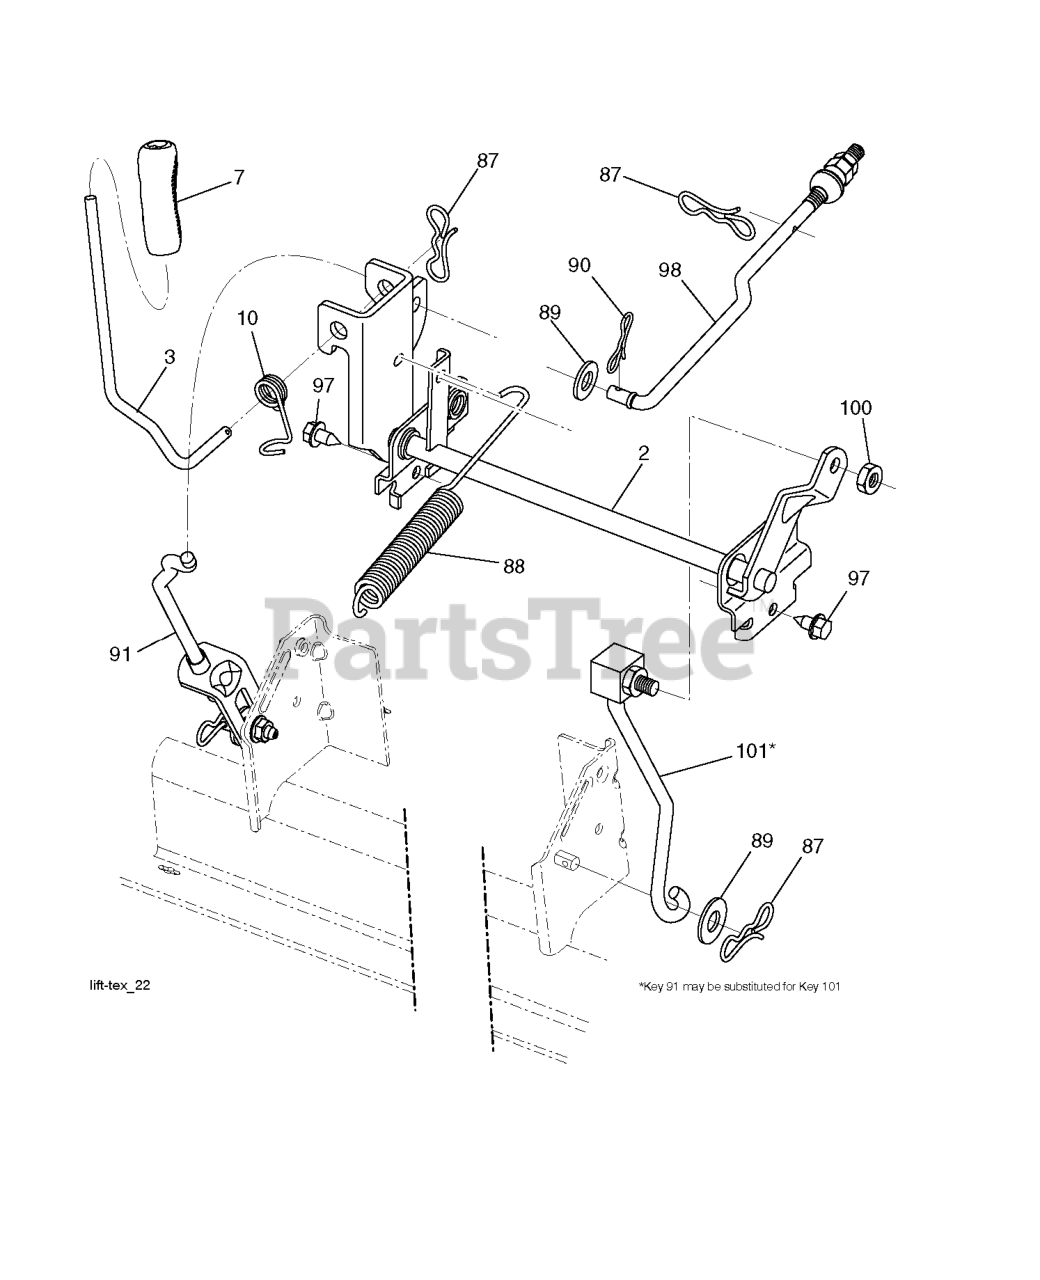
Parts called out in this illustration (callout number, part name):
2	SHAFT.ASM.CROSS.LIFT
3	LEVER.LIFT.HANDLE.LT
7	GRIP.HANDLE.LIFT.PVC.BLACK
10	SPRING.TORSION.LIFT.HANDLE
87	PIN.COTTER.7/16.BOW TI.
88	SPRING.LIFT.ASSIST
89	WASHER.CLEAR.ZINC
90	PIN.COTTER.5/16.BOW TI
91	LINK.ASM.LIFT.REAR
97	SCREW, 3/8-16X3/4
98	LINK.ASM.SUSP.FRONT.MW
100	LOCKNUT
101	LINK.ASM.LIFT.FIXE.38/42/46"
